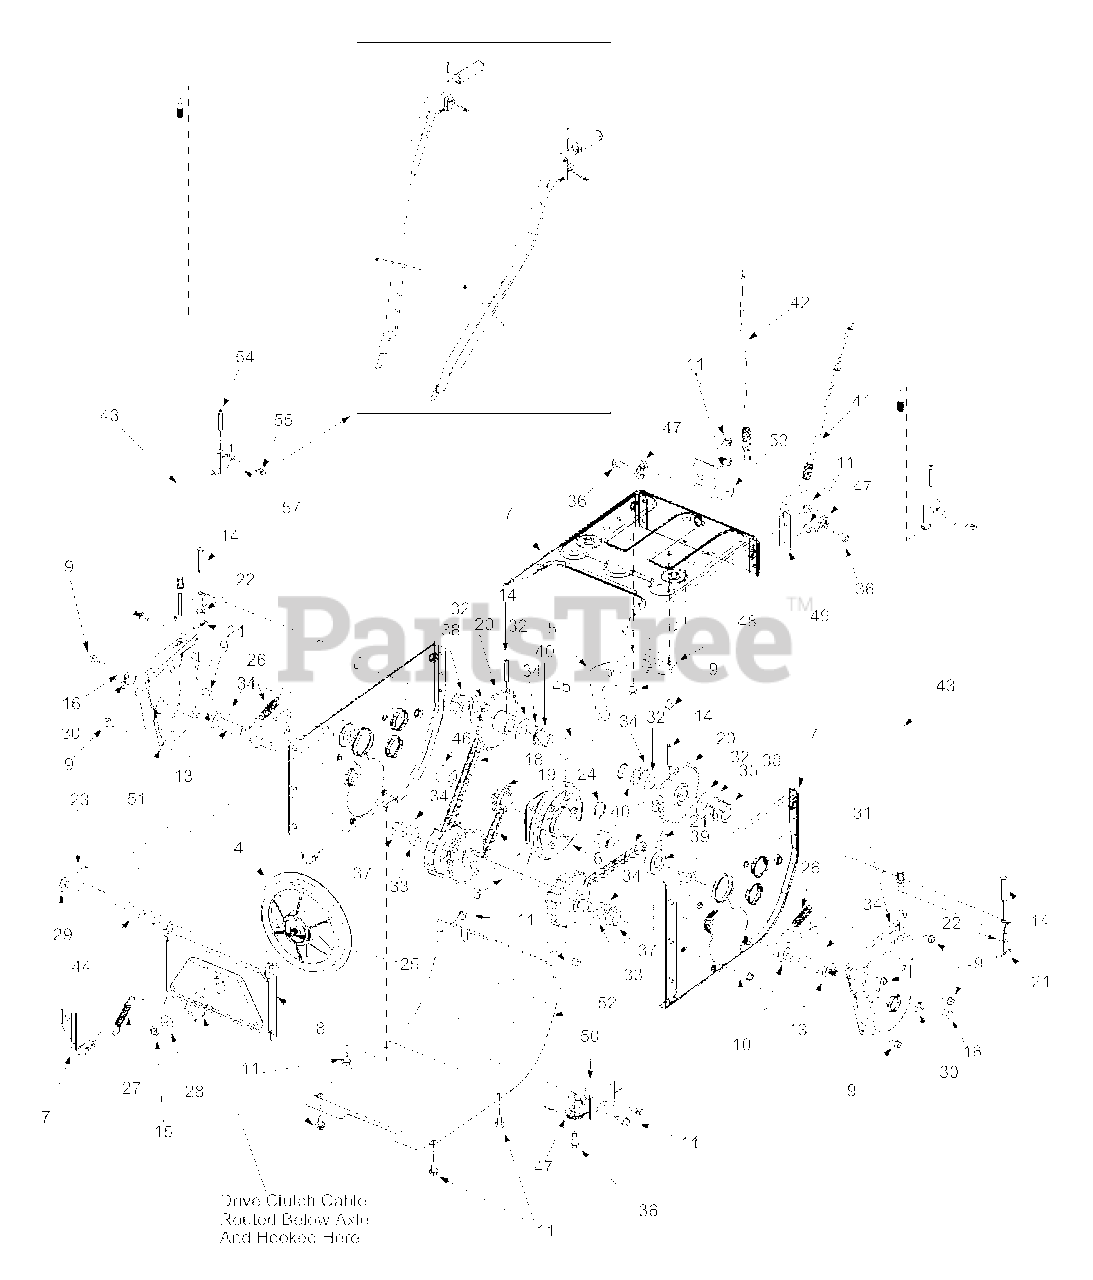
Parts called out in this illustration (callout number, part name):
1	Dogg Assembly: RH
3	Shift Assembly: Steerable Drive
4	Friction Wheel Disc Assy.
6	Bearing
10	Hex Washer Screw 1/4-20 x 1
11	Hex Screw 1/4-20 x .625"
13	Actuator Shaft
15	Jam Nut 3/8-24 Gr.8
16	Hex Nut: 3/8-16
17	Chain
18	Chain
19	Sprocket: 10T
20	Sprocket
21	Cotter Pin
22	Flat Washer
23	Cotter Pin
24	Snap Ring
25	Adhesive: Loctite
26	Extension Spring
27	Extension Spring
28	Bell Washer
29	Flat Washer
30	Lock Washer
33	Flat Washer
34	Lubricant: 6 in 1
35	Grease
36	Shoulder Screw
37	Hex Flange Bearing
38	Hex Flange Bearing
39	Ball Bearing
40	Flange Bushing
41	Auger Clutch Cable
42	Drive Clutch Cable
43	Steering Cable
44	Spacer
45	Axle Support Tube
46	Spacer
47	Roller Cable
55	Weld Nut
57	Turn Trigger
